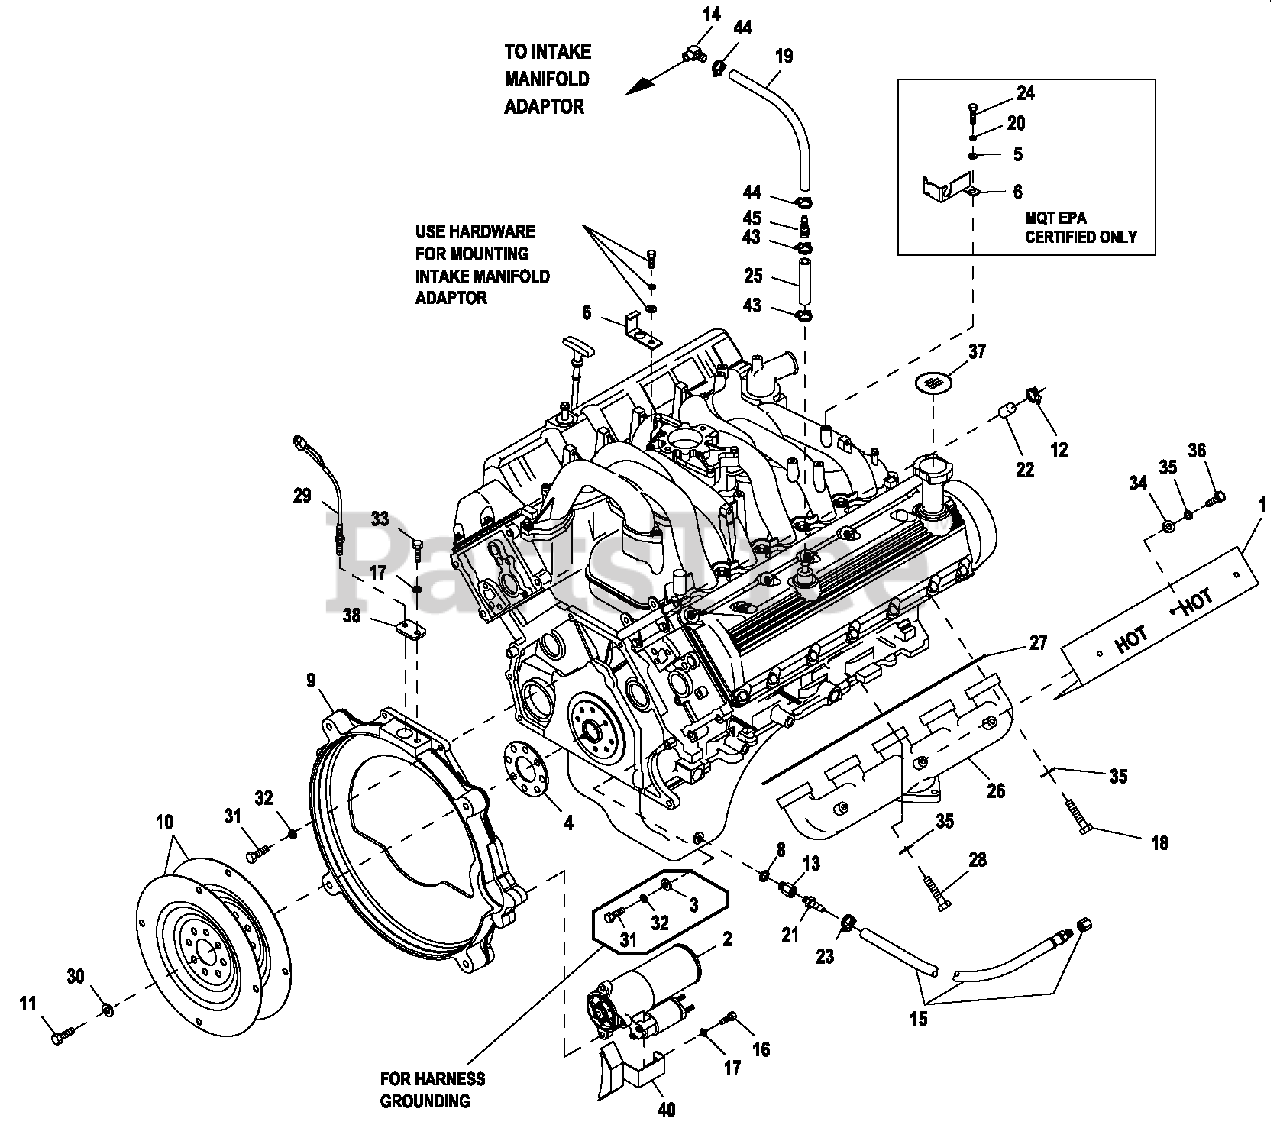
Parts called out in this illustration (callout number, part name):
1	HEAT SHIELD EXHAUST
2	STARTER MOTOR FORD V-10 ENGINE
3	WASHER FLAT 3/8-M10 ZINC
4	SPACER FLEXPLATE 5.4L/6.8L (1800 RPM UNITS ONLY)
5	WASHER FLAT 1/4-M6 ZINC
6	BRACKET SIGNAL CONDITIONER
8	WASHER NYLON .565
9	ENGINE ADAPTER 5.4L/6.8L
10	FLEX PLATE 2 POLE (1800 RPM UNITS ONLY)
11	SCREW HHC M10-1.0X 25 G10.9
12	CLAMP HOSE #10 .56 - 1.06 (1800 RPM UNITS ONLY)
13	ADAPTER M14-1.50X3/8NPT
14	BARBED EL 90 1/4NPTX 3/8
15	HOSE DRAIN ASSY 28"
16	SCREW HHC M8-1.25X30 G8.8
17	WASHER LOCK M8-5/16
18	SCREW SHC M8-1.25 X 35 SS
19	HOSE 3/8 ID SINGLE BRAID
20	WASHER LOCK M6-1/4
21	BARBED STR 3/8 NPTX 3/8
22	CAP HOSE (1800 RPM UNITS ONLY)
23	CLAMP HOSE .38- 87
24	SCREW HHC M6-1.0 X 16 G8.8
25	HOSE COOL 5/8" ID 250#WP (14")
26	EXH MANIFOLD MACH 6.8L V-10
27	GASKET EXHAUST MANIFOLD
28	SCREW HHC M8-1.25 X 35 SS G8.8
29	ASSY MAGPICKUP (3/8-24 MALE)
30	WASHER FLAT .43X1.00
31	SCREW SHC M10-1.5X25G12.9
32	WASHER LOCK M10
33	SCREW HHC M8-1.25X20 G8.8
34	WASHER FLAT M8 SS
35	WASHER LOCK M8 SSTL
36	SCREW HHC 5/16-18X1/2 SSTL
37	DECAL REFER TO OWNERS MANUAL
38	PLATE MAG PICK-UP ADAPTOR
40	COVER STARTER 5.4 & 6.8 FORD CPL
43	CLAMP HOSE BAND .88"
44	CLAMP HOSE BAND .63
45	HOSE BARB REDUCER 5/8"-3/8"ID
